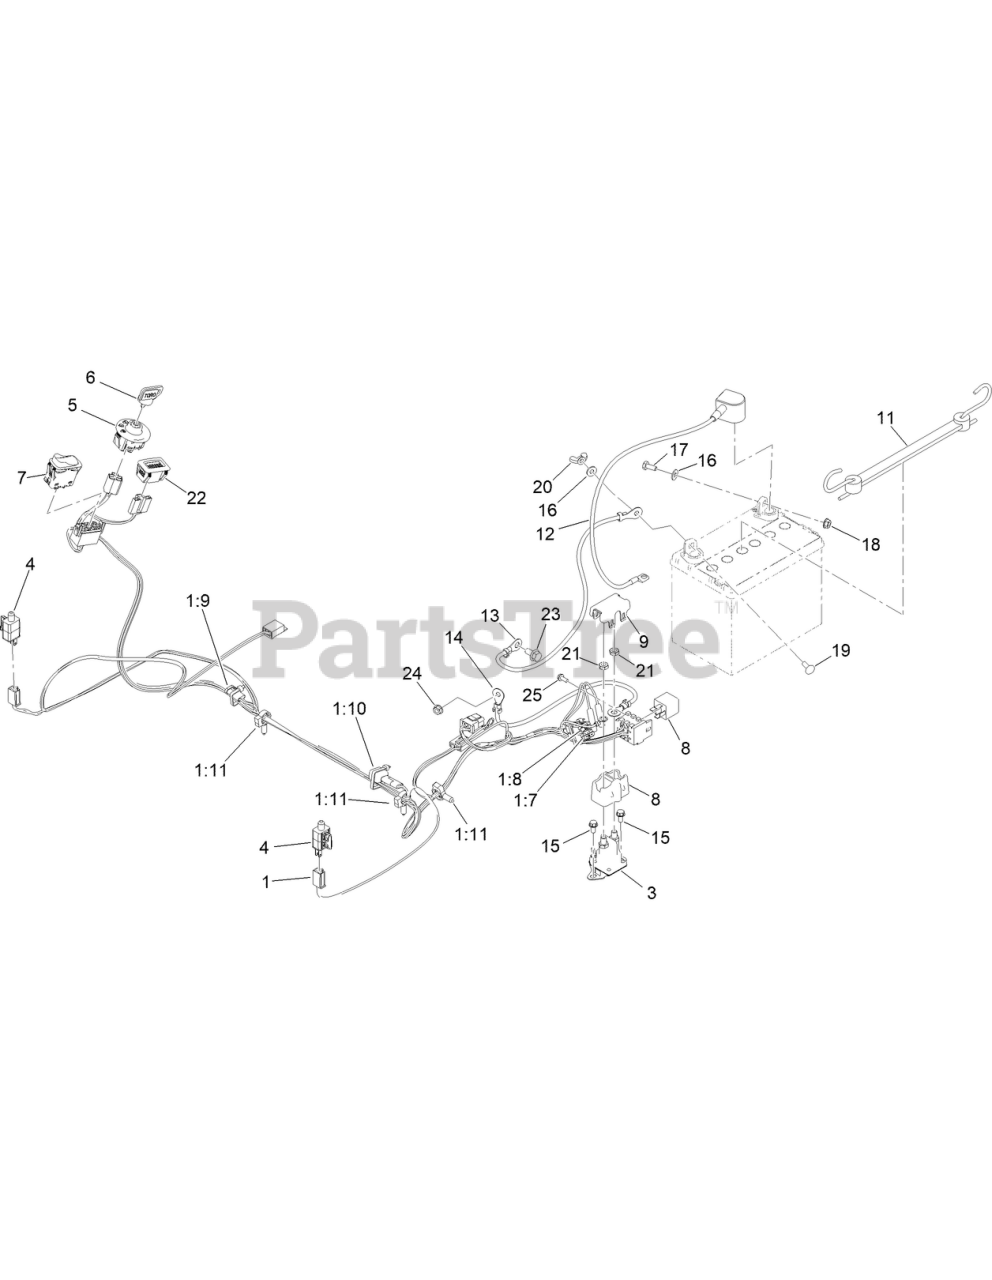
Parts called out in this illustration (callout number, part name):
1	HARNESS-WIRE, MAIN
1:7	FUSE-BLADE, 15 AMP
1:8	FUSE-BLADE, 25 AMP
1:9	CAP-OVER MOLD, 1M/1F
1:11	CLIP-TUBING, HARNESS
3	SOLENOID
4	SWITCH
5	SWITCH-IGNITION
6	KEY-IGNITION
7	SWITCH-ROCKER, ON-NONE-ON
8	COVER-SOLENOID
9	CAP-SOLENOID
11	HOLDDOWN-BATTERY
12	CABLE-BATTERY,RED
13	CABLE-BATTERY, BLACK
14	CABLE-BATTERY, POSITIVE
15	SCREW-HWH
16	WASHER
17	SCREW-HH
18	NUT-HF
19	BOLT-CARR
20	NUT-WING
21	NUT-HJ
22	HOUR METER
23	SCREW-HHF
24	NUT-HF
25	SCREW-TAPTITE
